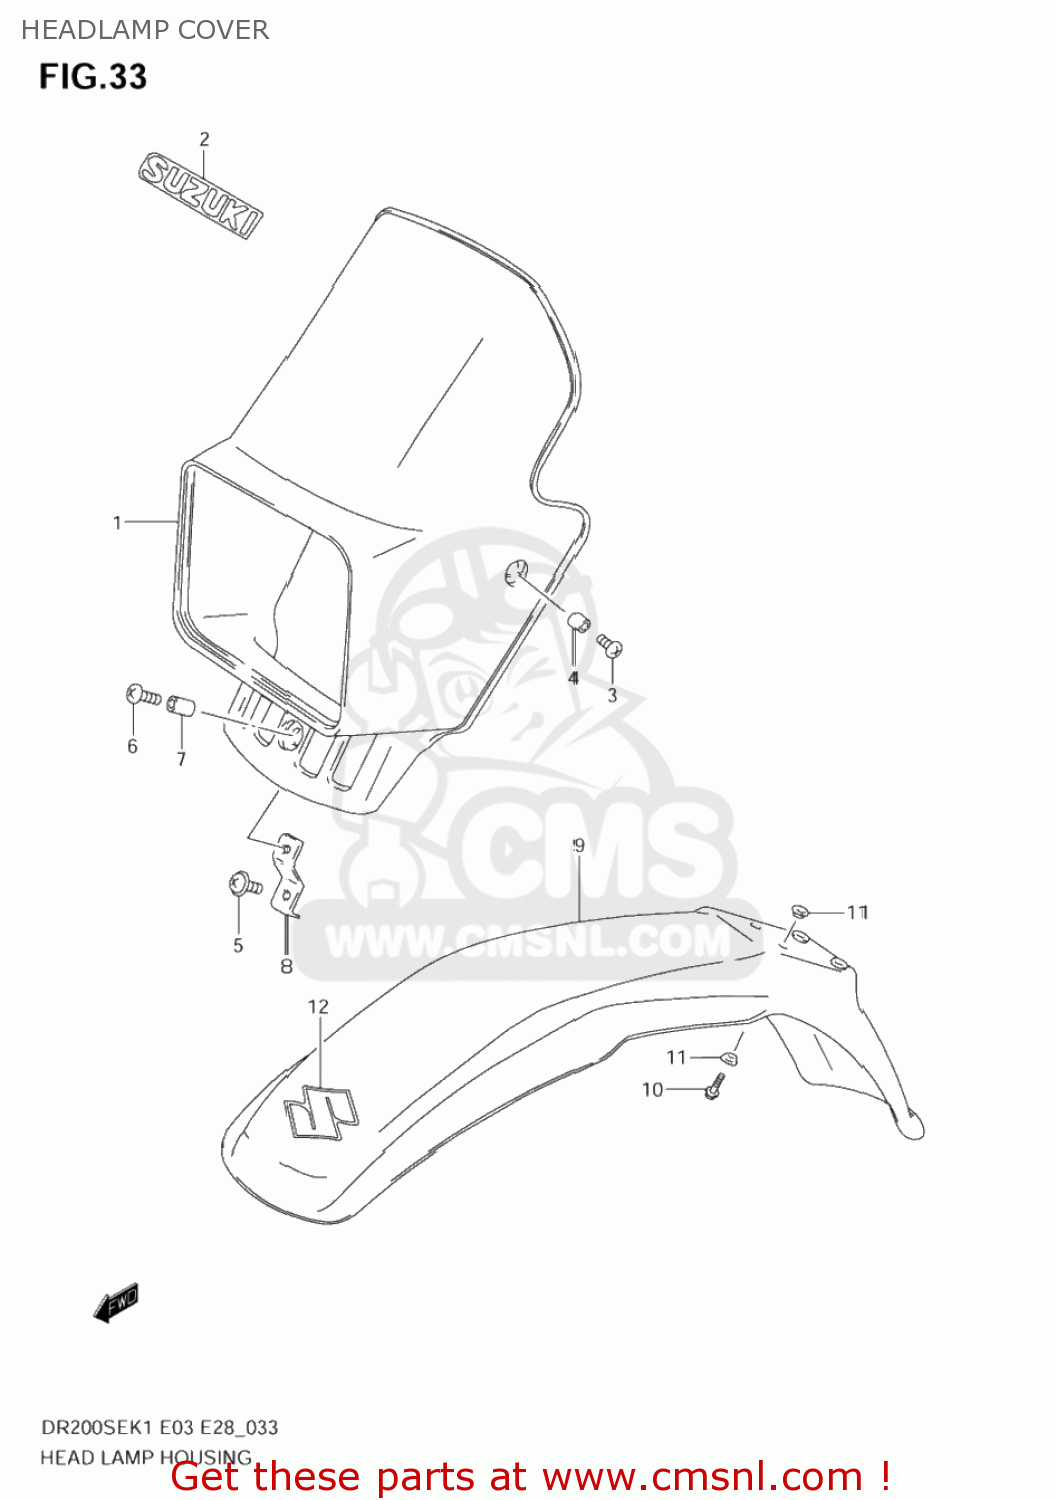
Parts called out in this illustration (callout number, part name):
1	COVER,HEADLAMP
2	EMBLEM,HEADLAMP COVER
3	SCREW 6X12
4	SPACER(6.1X8X3.5)
5	SCREW
6	SCREW
7	SPACER(6.1X8X12)
8	BRACE,HEADLAMP HOUSING LWR
9	FENDER,FR
10	BOLT
11	WASHER
12	EMBLEM,S
